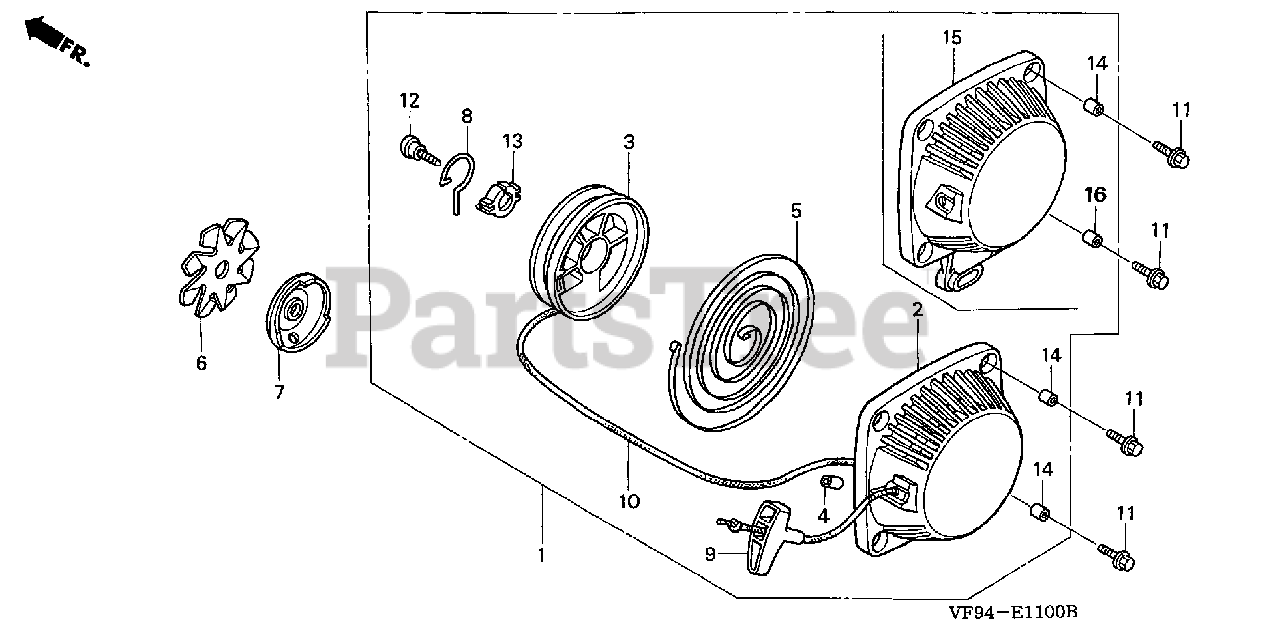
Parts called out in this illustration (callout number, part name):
1	STARTER ASSY., RECOIL *NH1* (BLACK)
3	REEL, RECOIL STARTER
4	GUIDE, ROPE
5	SPRING, RECOIL STARTER
6	FAN, RATCHET
7	PULLEY, RECOIL STARTER
9	KNOB, RECOIL STARTER
10	ROPE, RECOIL STARTER (#3.5X40")
11	BOLT, FLANGE (5X18)
12	SCREW, SETTING
15	CASE, RECOIL STARTER *NH1* (BLACK)
16	COLLAR A, HEAD COVER
